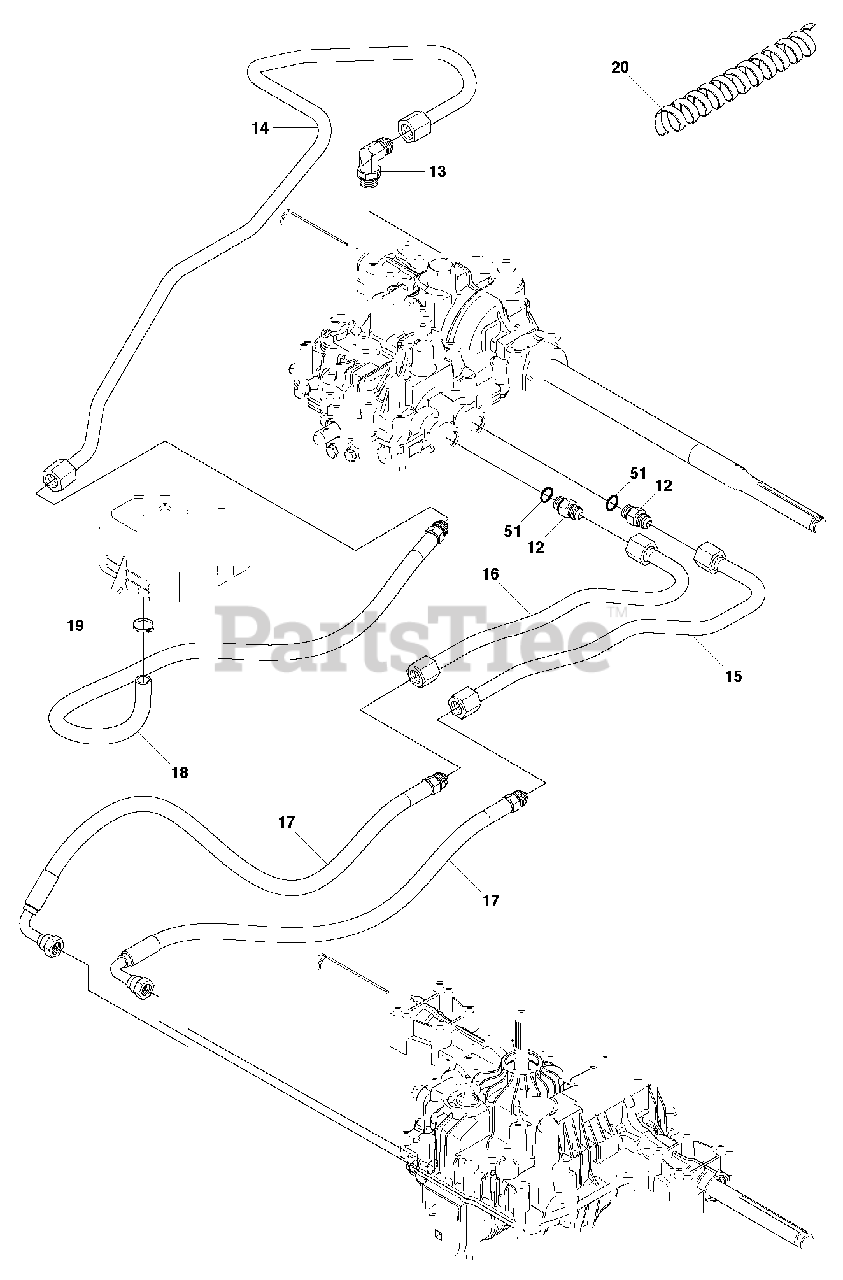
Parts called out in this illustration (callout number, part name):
12	PIPE FITTING
14	HYDRAULIC PIPE
15	HYDRAULIC PIPE
16	HYDRAULIC PIPE
17	HYDRAULIC HOSE
19	HOSE CLIP
20	PROTECTOR
